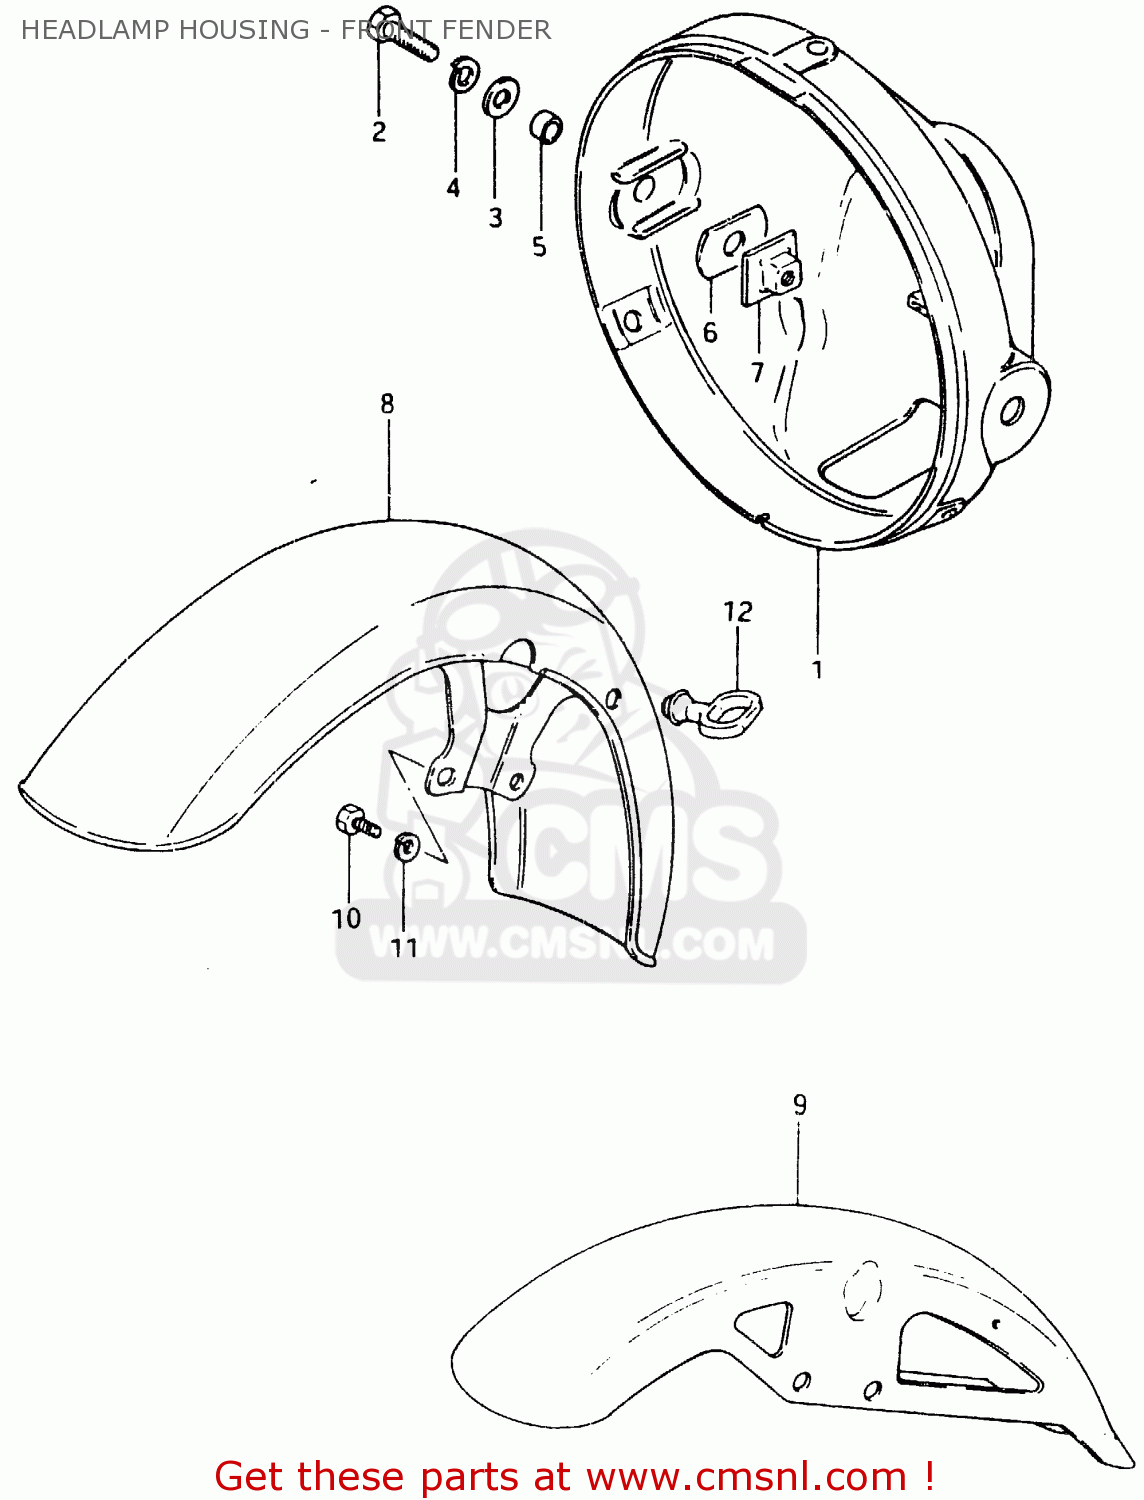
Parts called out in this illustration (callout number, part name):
1	HOUSING,HEADLAMP
2	BOLT
3	WASHER
4	LOCK WASHER
5	SPACER (8.8X12X7)
6	CUSHION
7	PLATE,HEADLAMP HOUSING
8	FENDER, FRONT
9	FENDER, FRONT
10	BOLT
11	LOCK WASHER
12	GUIDE,CABLE
